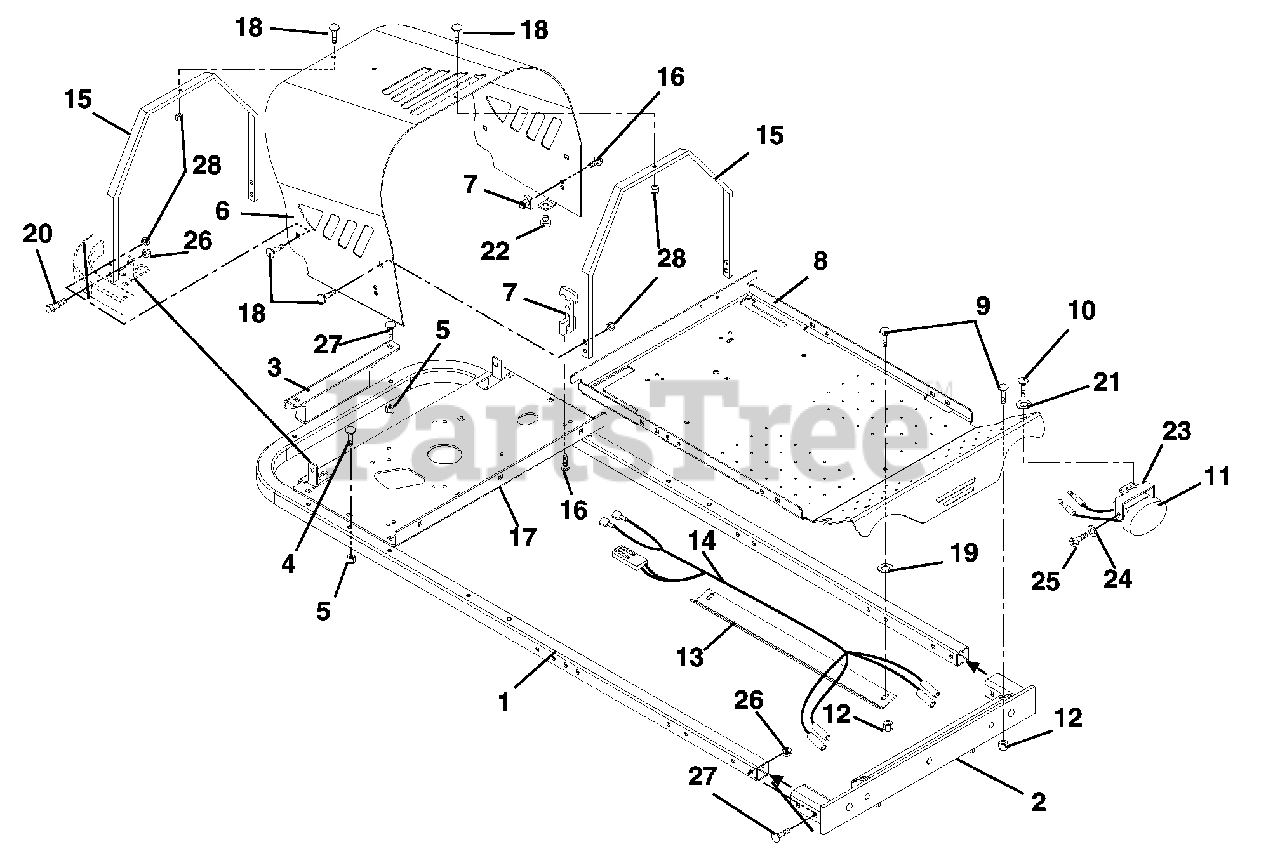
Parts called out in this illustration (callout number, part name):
1	TUBE-FRAME BLK
2	WMT, AXLE MOUNT
3	TRAILER HITCH W/DECALS
4	@BLT-RDHDSQNK .38-16X2.50 G5YZ
5	@NUT-LK-NYL-FLG .38-16 YWZC
6	HOOD, ZOOM
7	LATCH, RUBBER
8	FOOTREST
9	@BLT-RDHDSQNK .31-18X1.00 G5YZ
10	SCR-CAP BTHD.31-18X.50 GR5 YZ
11	LIGHT-CONS RIDE ON- SEE B-2124
12	@NUT-LK-NYL-FLG .31-18 YWZC
13	BKT-HARNESS
14	HARNESS, LIGHT
15	BRACE, HOOD
16	@SCR-MCH 10-24X.50 HWH YWZC
17	PLATE, ENGINE
18	@BLT-RHDSSQNK .31-18X.62 G5YZ
19	WSHR-FL-STL .328X.87X.179 YWZC
20	BOLT-SHLDR .375-16X.150
21	@WSHR-LK .31X.078 REG YWZC
22	BUTTON BUMPER
23	WMT, LIGHT BRACKET
24	WSHR-LK 4MMX1MM REG CL ZINC
25	SCREW-M4X.07X8 SHCS CLZNC
26	@NUT-LK-TOP-FLG .38-16 YWZC
27	@BLT-RDHDSQNK .38-16X2.25 G5YZ
28	@NUT-LK-TOP-FLG .31-18 YWZC
